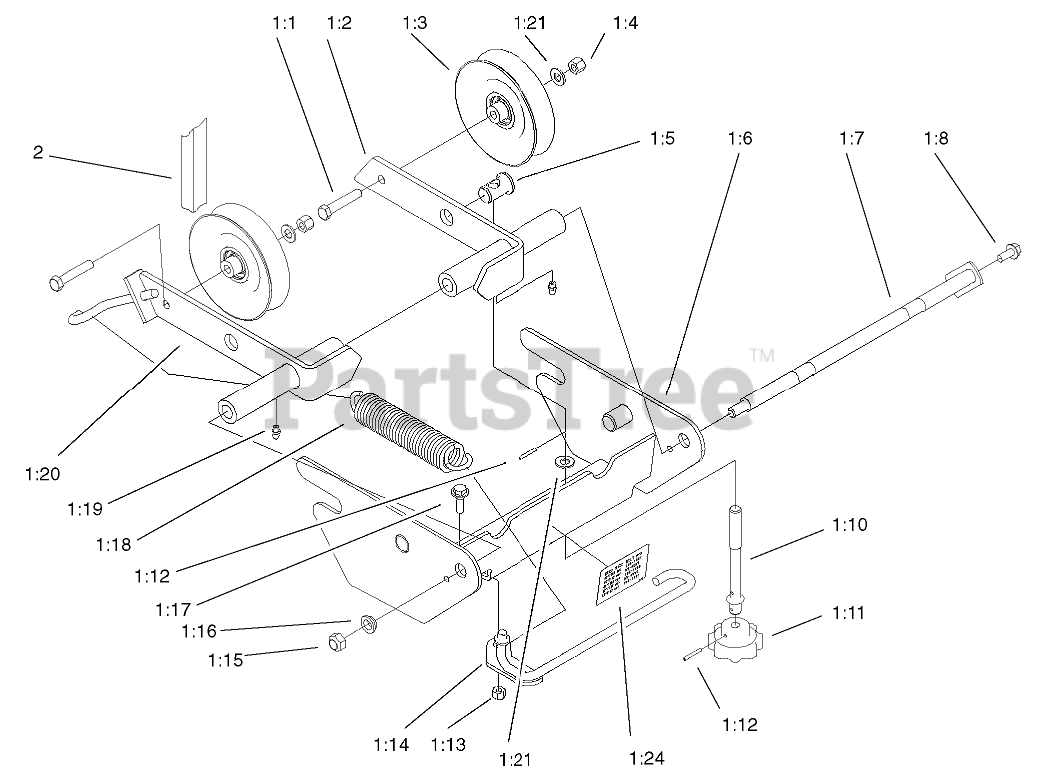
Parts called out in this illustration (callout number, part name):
1:1	SCREW-HH
1:2	LH Tension Bracket ASM
1:3	PULLEY-IDLER
1:4	NUT-LOCK, NI
1:5	Ferrule-Adjuster
1:6	Pulley Box ASM
1:7	ROD-PIVOT
1:8	SCREW-HWHTF
1:10	Rod-Tension
1:11	Knob-Adjusting
1:12	PIN-ROLL
1:13	NUT-LOCK, NI
1:14	TENSIONER-IDLER
1:15	NUT-LOCK, NI
1:16	Spacer-Shoulder
1:17	SCREW-SHOULDER
1:18	SPRING-EXTENSION
1:19	FITTING-GREASE
1:20	RH Tension Bracket ASM
1:21	WASHER-PLAIN
1:23	WASHER
1:24	DECAL-PULLEY BOX
2	BELT-V
